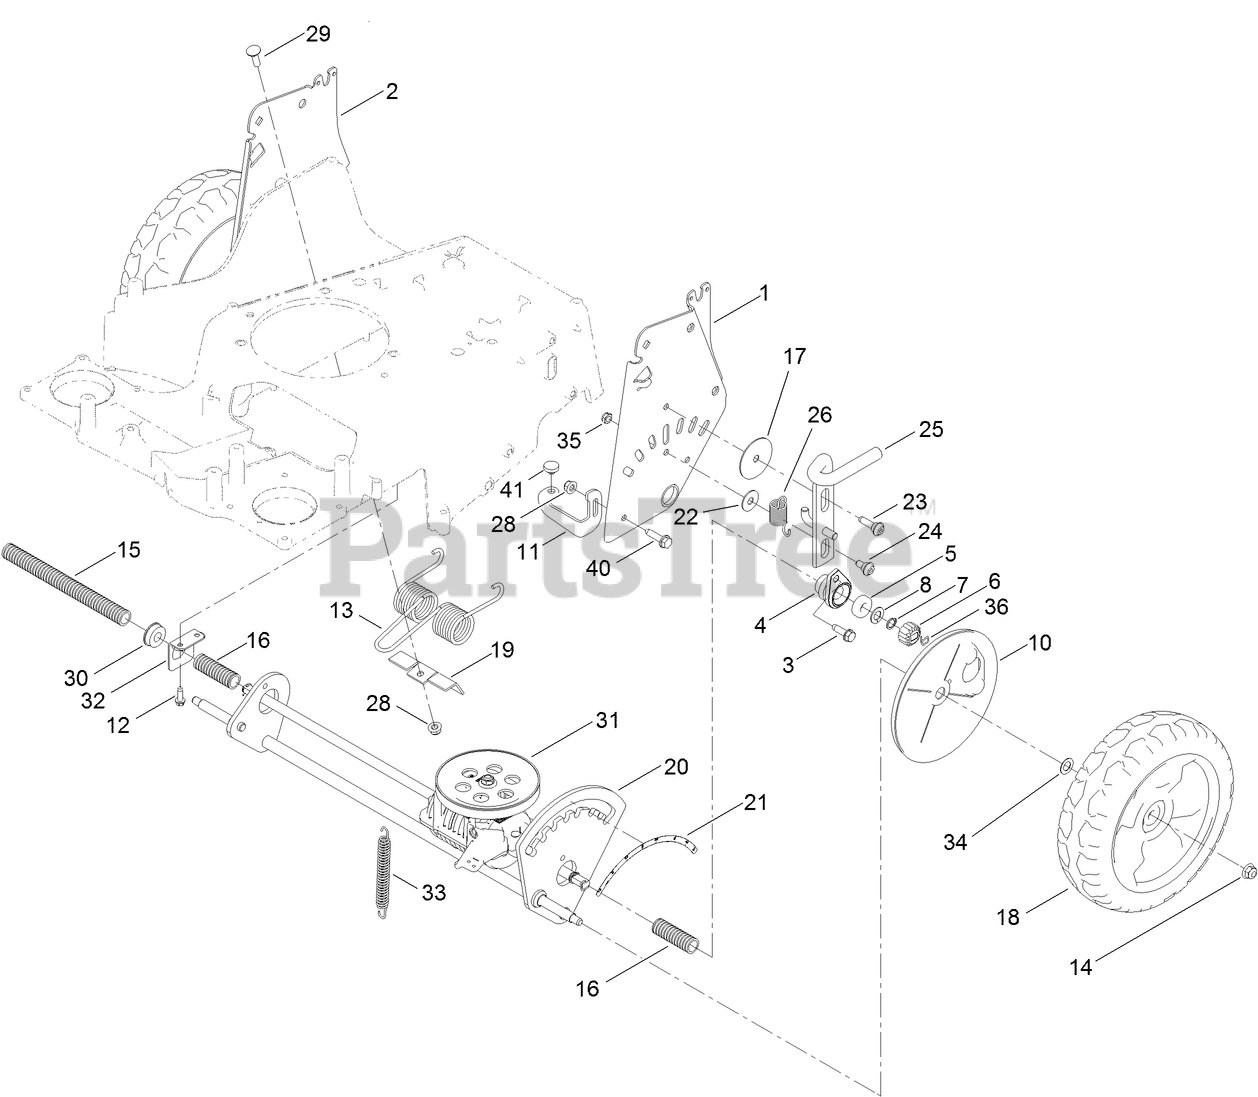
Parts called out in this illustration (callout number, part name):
1	LH HOC PLATE ASM
2	RH HOC PLATE ASM
3	SCREW-THD ROLL, HWH
4	RETAINER-BEARING
5	BEARING-BALL
6	GEAR-PINION, 15T
7	RING-RETAINING
8	WASHER-THRUST
10	COVER-GEAR
11	BRACKET-STOP, ADJUSTABLE
12	SCREW-HWHTF
13	SPRING-TORSION
14	NUT-HF, NI
15	CONDUIT-CONVOLUTED
16	CONDUIT-CONVOLUTED
17	WASHER-PLAIN
18	10.5 INCH WHEEL ASM
19	BRACKET
20	AXLE-REAR
21	DECAL-HOC, REAR
22	WASHER
23	SCREW-SHOULDER, BHTF
24	BOLT-SHOULDER
25	LOCK-HEIGHT, ADJUST
26	SPRING-EXTENSION
28	NUT-HF, NI
29	BOLT-CARR
30	BEARING-BALL
31	TRANSMISSION KIT
32	MOUNT-BEARING
33	SPRING-EXTENSION
34	WASHER-PLAIN
35	NUT-LOCK, NI
36	PIN-SNAP
40	SCREW-HWHTF
41	BUMPER
